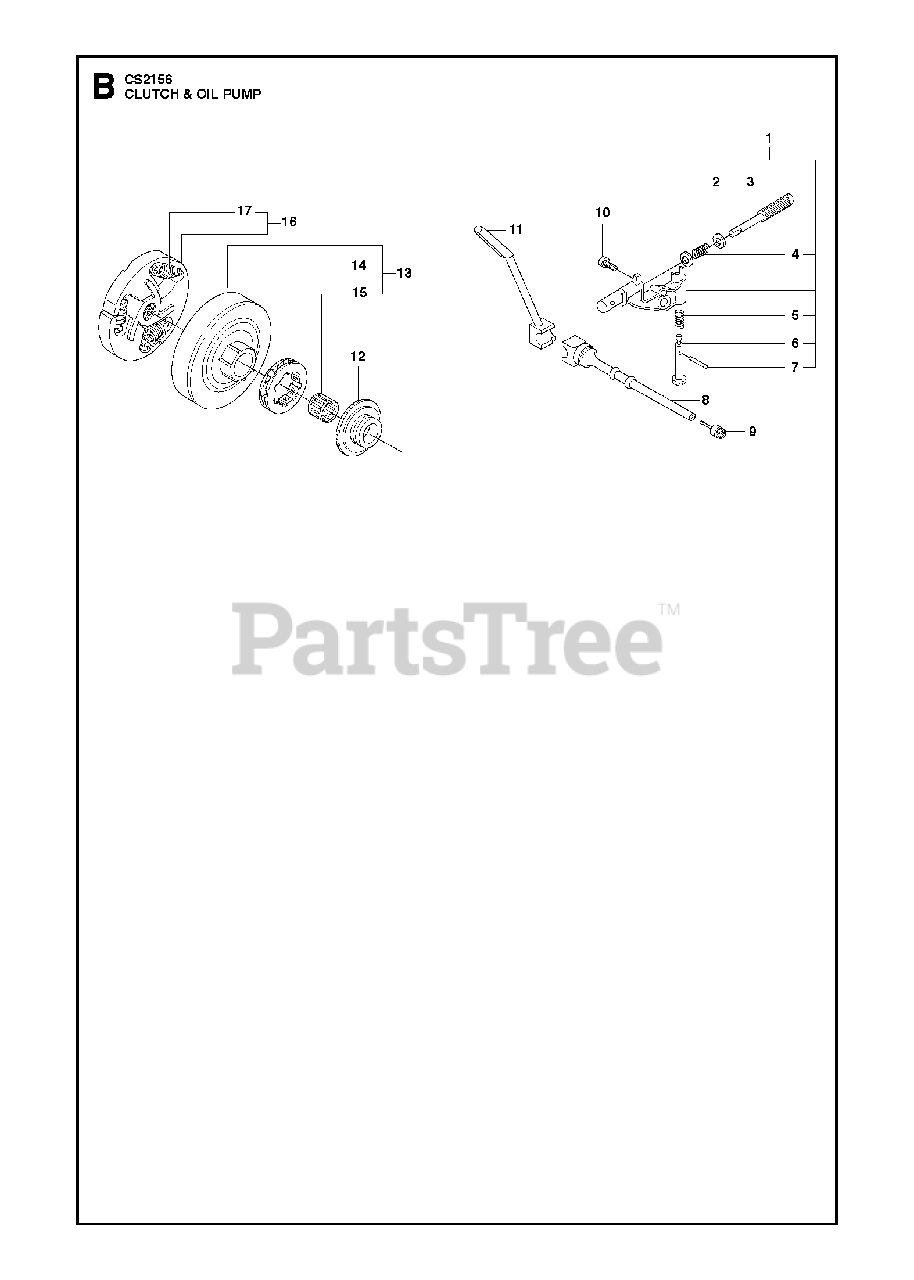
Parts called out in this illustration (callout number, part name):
1	OIL PUMP ASSY
2	WASHER
3	PUMP PISTON
4	SPRING
5	SPRING
6	SCREW
7	PIN
8	HOSE
9	OIL PLUMMET
12	PUMP GEAR
13	CLUTCH DRUM
14	RIM SPROCKET 7T .325
14	68210 RIMSPROCKET
15	NEEDLE BEARING
16	CLUTCH
17	SPRING
